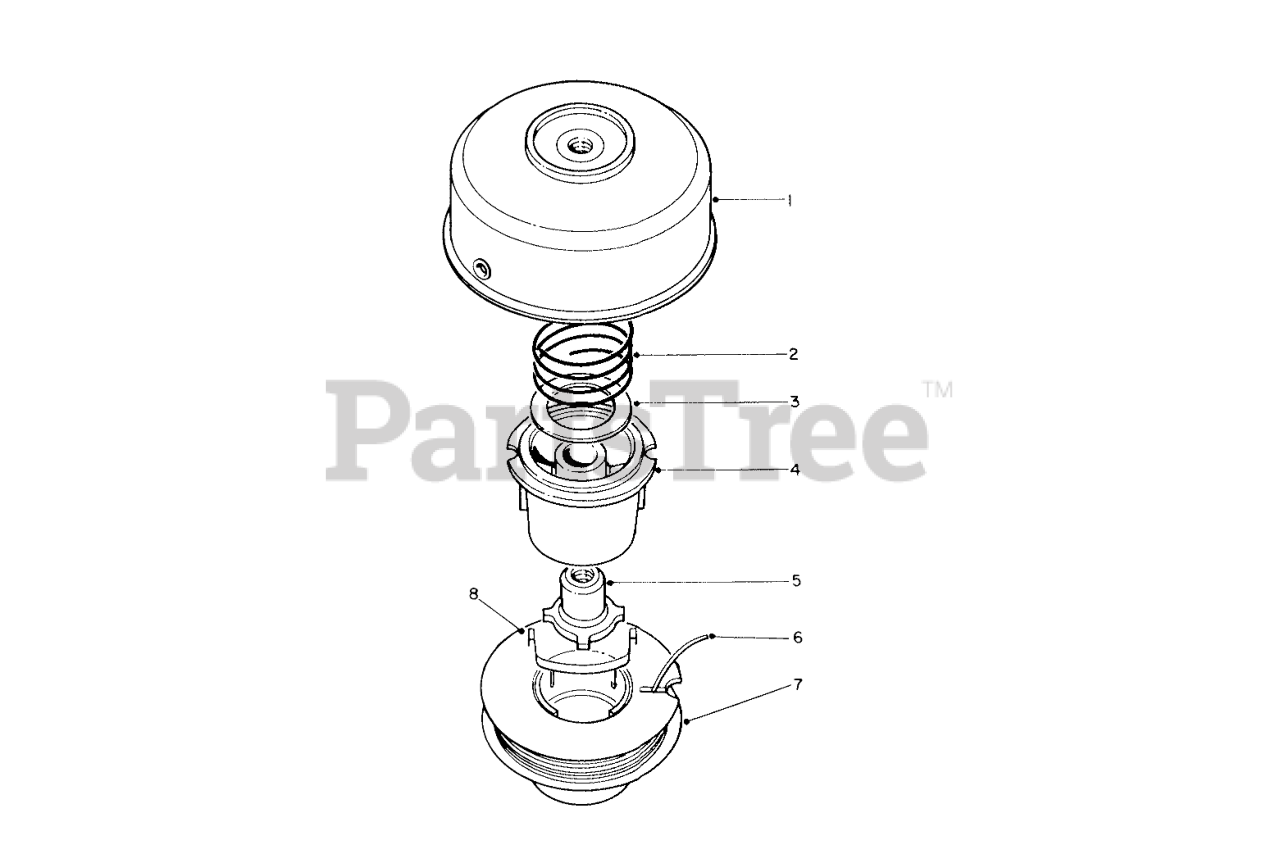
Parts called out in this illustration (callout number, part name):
1	DRUM EYELET ASM
2	SPRING
3	WASHER-FLAT
4	SPOOL CORE
5	LH DRIVER
6	Line-Cutting .095 Dia.
7	Spool Prewound .95 Dia. 30- (Incl. Ref. #8)
8	SADDLE-SPOOL CAP
